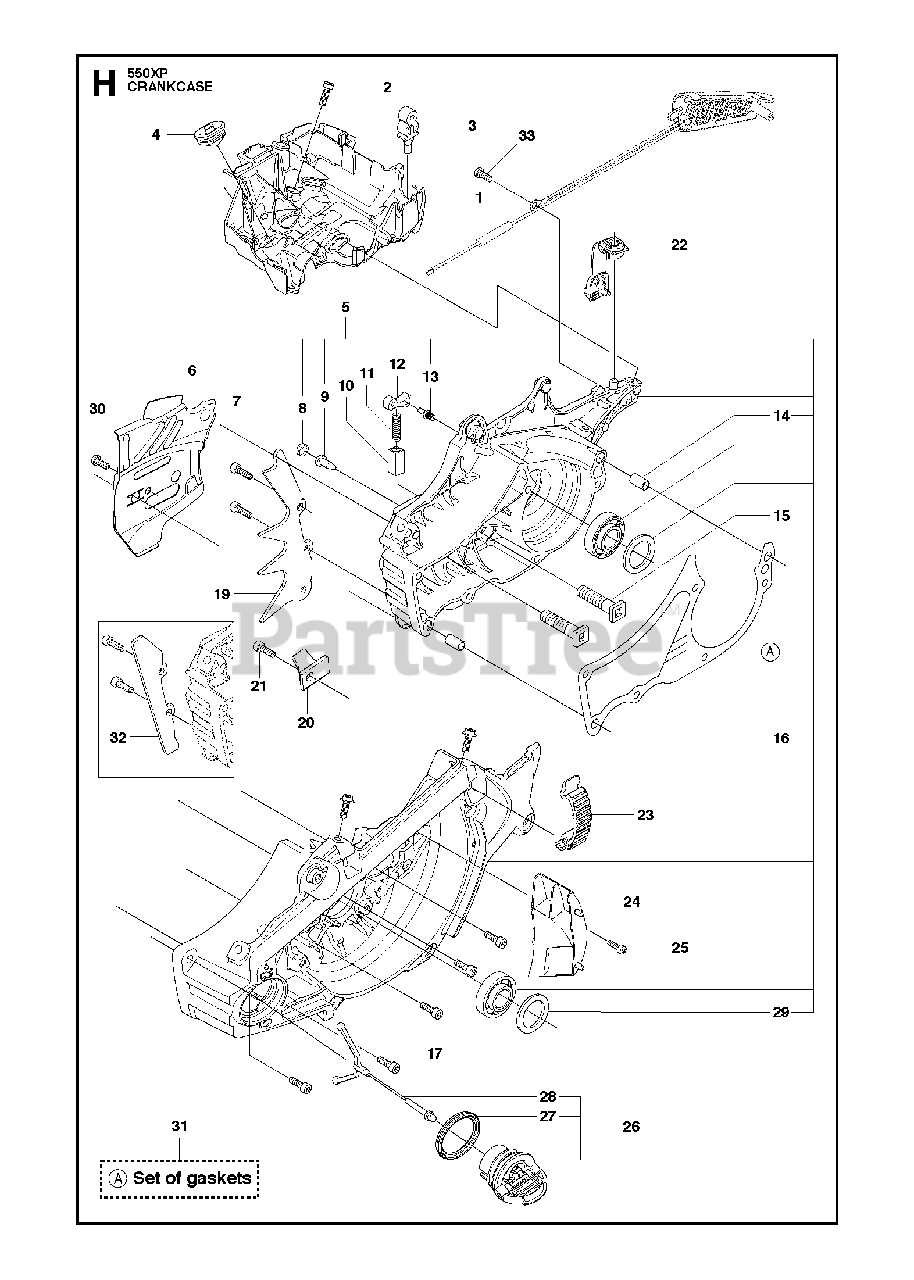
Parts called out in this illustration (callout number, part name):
1	CARBURETTOR AREA BASE
5	CRANKCASE ASSY SPARE PART_H55
6	CHAIN GUIDE PLATE
8	PLUG
9	VALVE-CHECK (DUCKBILL)
11	LOCK SPRING
13	PIN
14	SLEEVE
15	BAR BOLT
16	SCREW IHSCM
17	SCREW IHSCM
20	CHAIN CATCHER
22	DEFLECTION LIMITER
23	CLIP GRAY
24	AIR NOZZLE
25	SCREW IHSCM
26	Tank Cap Assembly
27	Tank Cap Gasket
28	TANK LOCK
29	RADIAL SEAL
30	SCREW CITXPANT
31	GASKET KIT 50CC
32	BUMPER, BAG
